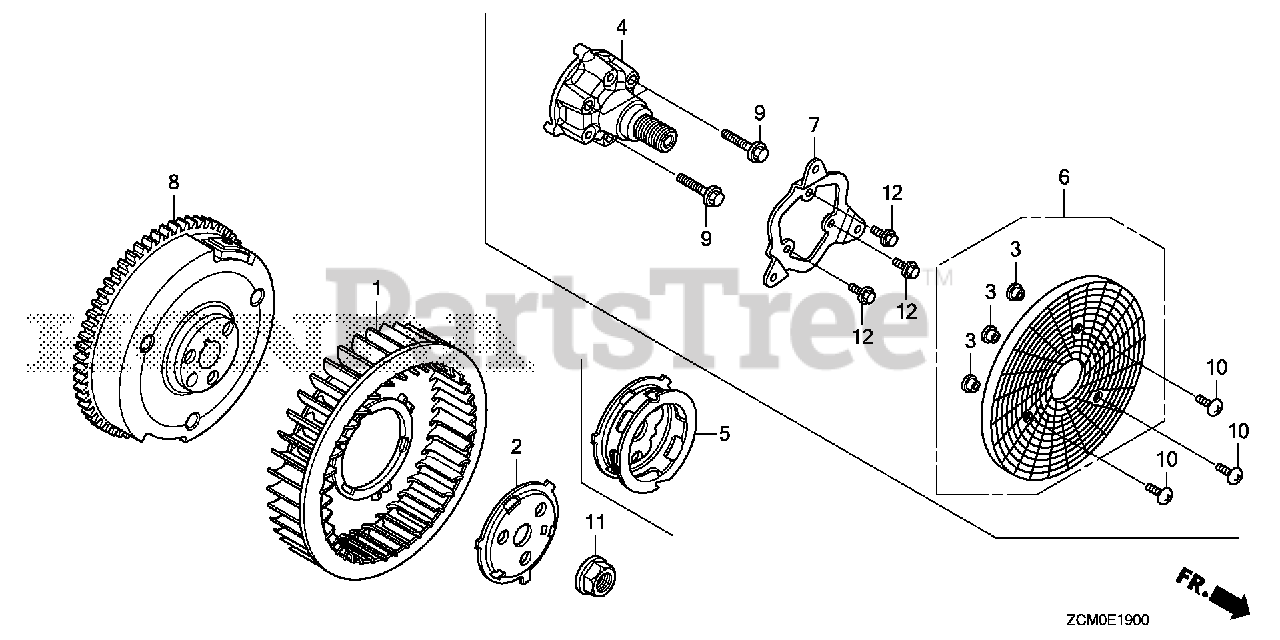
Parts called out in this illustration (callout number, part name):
1	FAN, COOLING
2	PLATE, COOLING FAN SETTING
11	NUT, SPECIAL (20MM)
